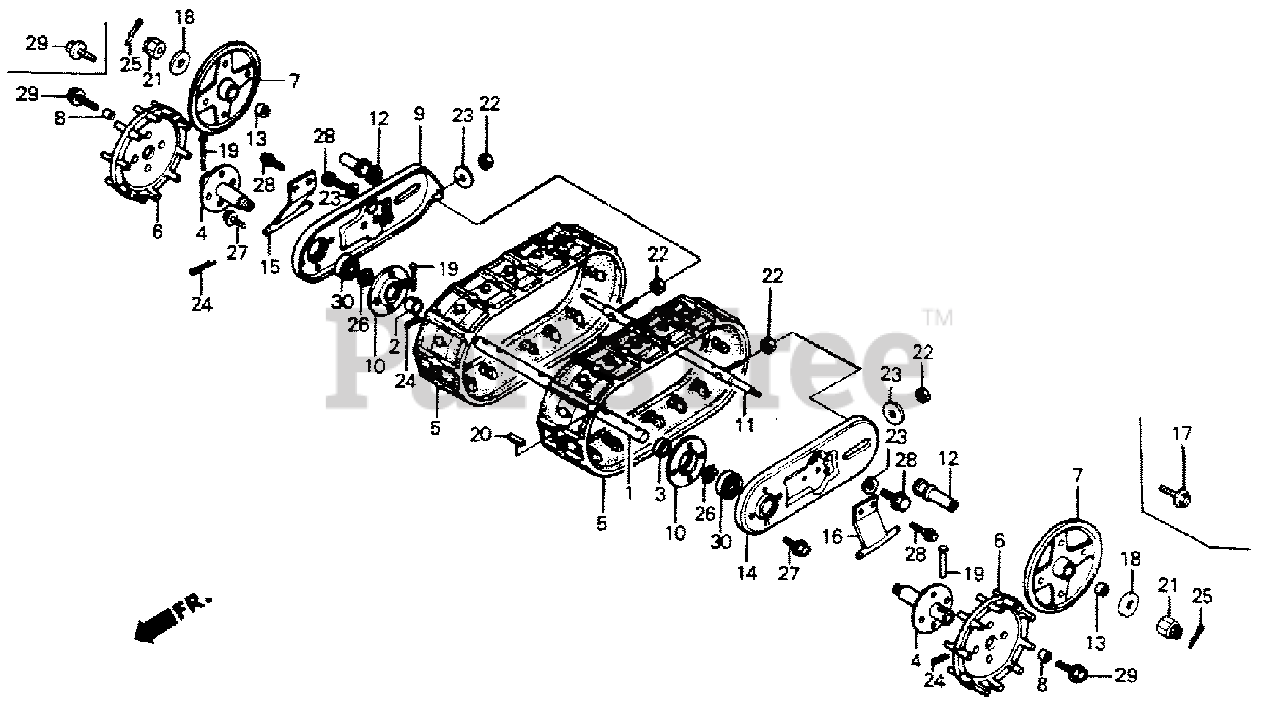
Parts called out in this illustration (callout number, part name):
1	SHAFT, WHEEL
2	COLLAR, WHEEL SHAFT
3	COLLAR, WHEEL SHAFT (B)
4	HUB, CRAWLER
5	CRAWLER (NOT AVAILABLE)
6	SPROCKET, CRAWLER
7	ROLLER, CRAWLER (NOT AVAILABLE)
8	COLLAR, SPROCKET (NOT AVAILABLE)
9	PLATE, R. CRAWLER
10	HOLDER, CRAWLER BEARING
11	PIPE, CRAWLER (NOT AVAILABLE)
12	SHAFT, ROLLER (NOT AVAILABLE)
13	BUSH, ROLLER
14	PLATE, L. CRAWLER
15	GUIDE, R. CRAWLER
16	GUIDE, L. CRAWLER
17	BOLT, L. (8X22)
18	WASHER, LOCK (8MM)
18	WASHER (12MM) (NOT AVAILABLE)
19	PIN (6.2X38)
20	KEY (5X5X21)
21	NUT, CASTLE (12MM)
22	NUT, HEX. (8MM)
23	WASHER, PLAIN (8MM)
24	PIN, COTTER (3.0X18)
25	PIN, COTTER (3.0X45)
26	CIRCLIP (OUTER) (25MM)
27	BOLT, FLANGE (6X10)
28	BOLT, FLANGE (8X14)
29	BOLT, FLANGE (8X20)
30	BEARING, RADIAL BALL (6005UU)
